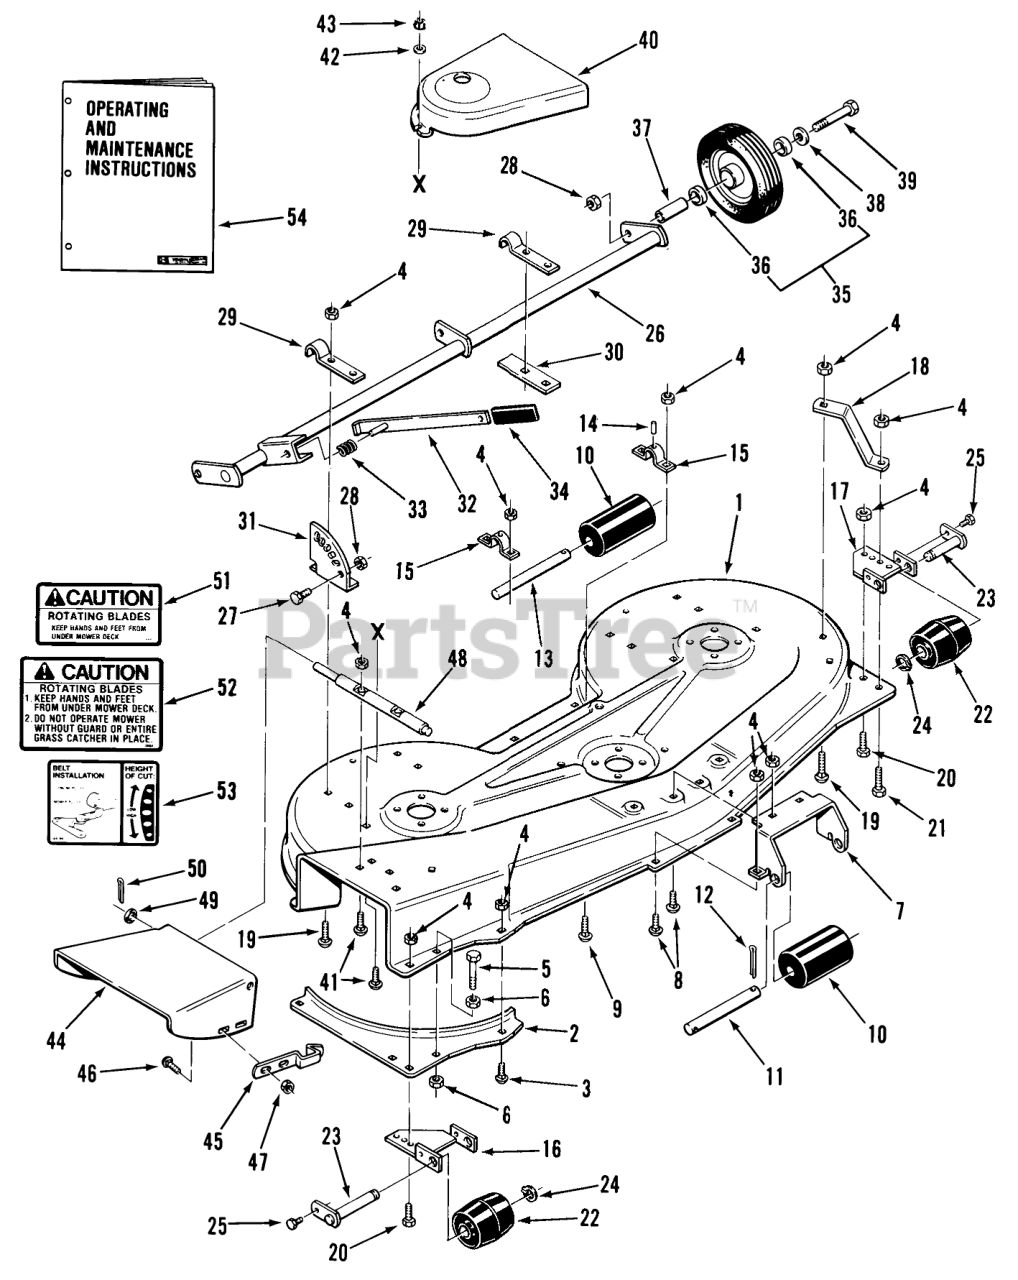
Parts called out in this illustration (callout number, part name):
3	CARRIAGE BOLT -4
8	CARRIAGE BOLT -4
10	ROLLER
14	SPIROL PIN
16	ASSY ROLLER BRKT *R
25	Bolt
33	SPRING-COMPRESSION
37	SPACER
40	COVER BELT RH
42	WASHER 5/16 SAE
44	CHUTE EXTENSION
54	Operating Maintenance Instructions
